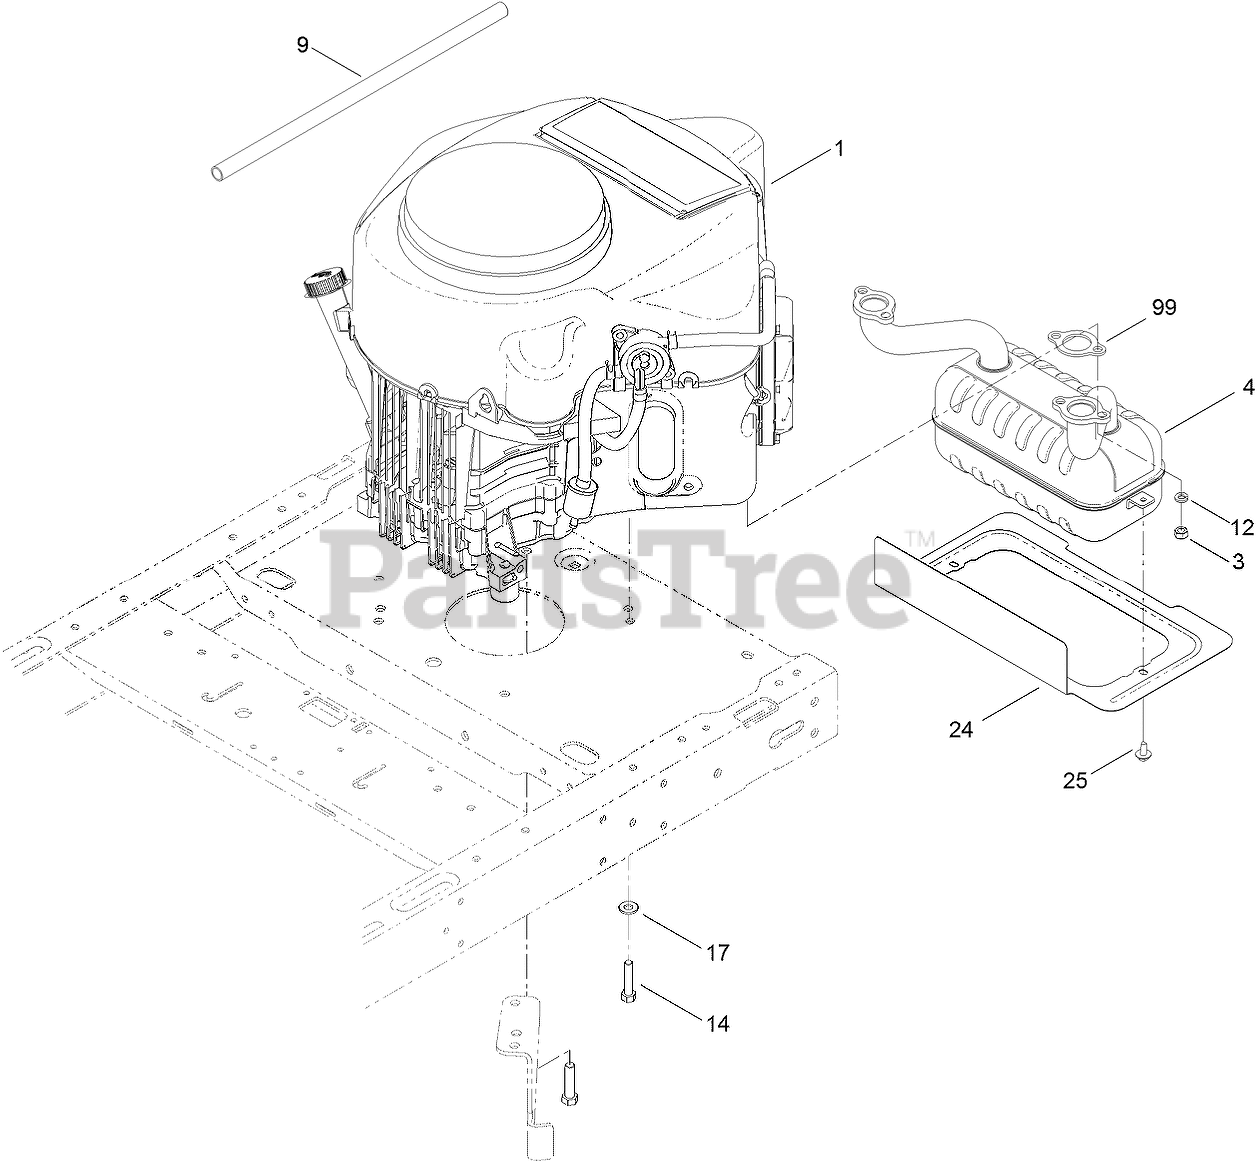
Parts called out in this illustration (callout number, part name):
4	MUFFLER-KAWASAKI
9	TUBE-DRAIN, OIL
12	WASHER-LOCK
14	BOLT-HH
17	WASHER-FLAT
24	SHIELD-HEAT
25	SCREW-HHFTF
99	GASKET-EXHAUST
